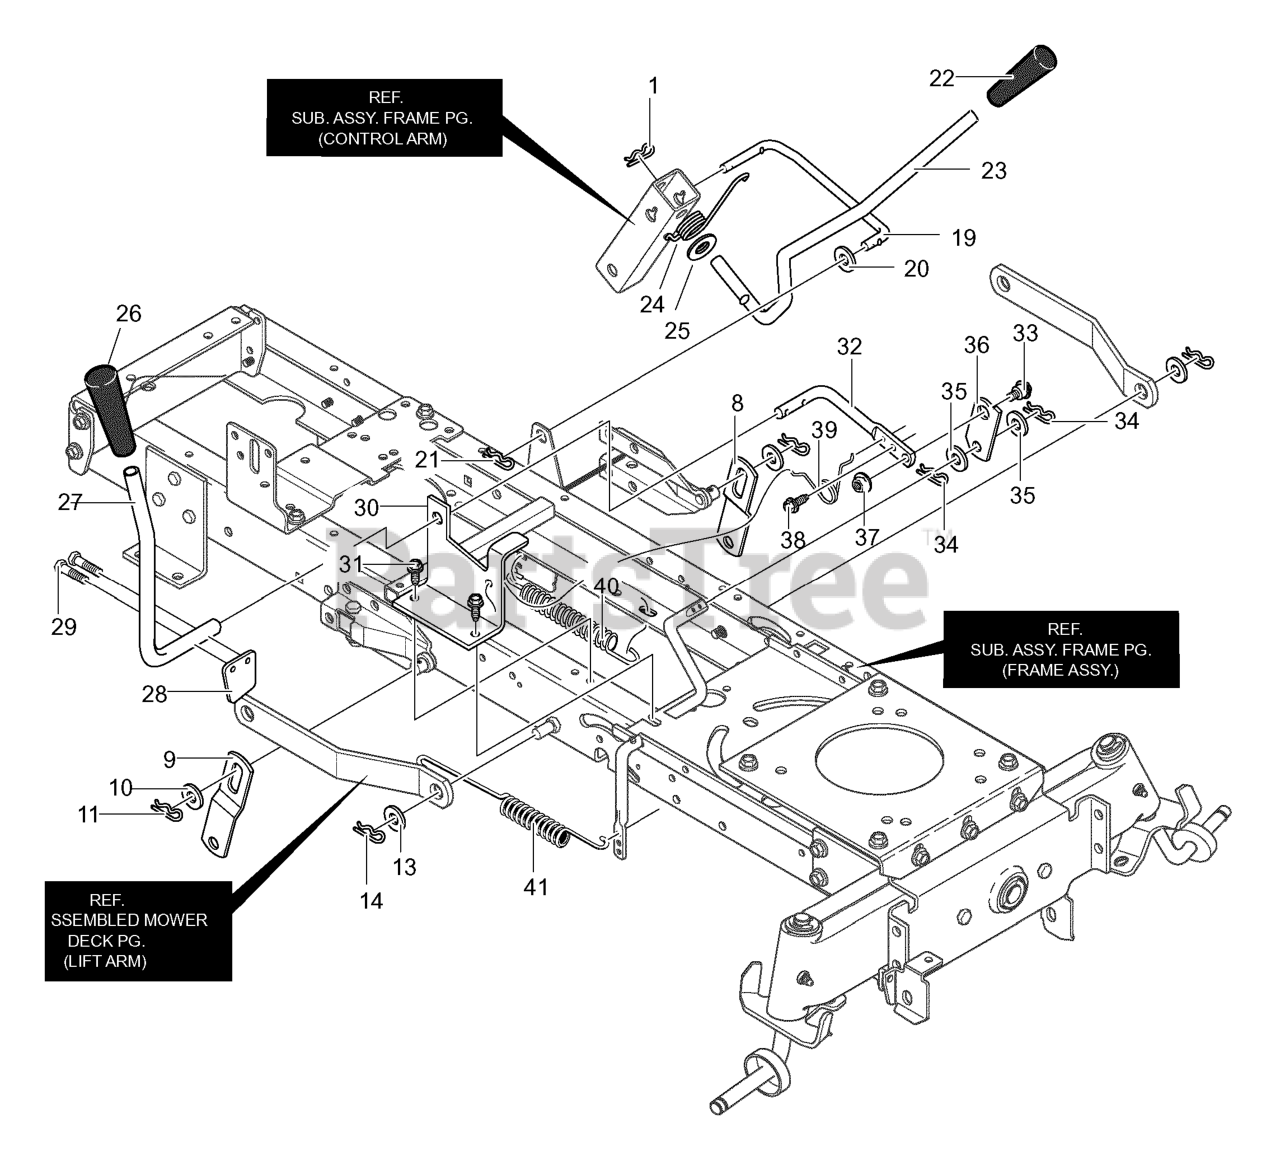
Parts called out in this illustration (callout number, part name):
1	Hair Pin
8	Link, Lift LH
9	Link, Lift RH
10	Flat washer
11	Hair Pin
13	Flat washer
14	Hair Pin
19	Link, Lift Handle
20	Flat washer
21	Hair Pin
23	Handle, Lift
24	Washer, Flat
25	Torsion Spring
27	PTO Handle
28	Paddle Switch
29	Screw, Thd Form
30	Bracket, PTO
31	Screw, 5/16-18 x 0.50 (26x277)
32	Lever, PTO
33	Bolt, Shoulder 3/8-16
34	Hair Pin
35	Washer, Flat
36	Link PTO
37	Nut, 3/8-16
38	Screw, 5/16-18 x 0.75
39	Torsion Spring
41	Spring, Extension (165x118)
